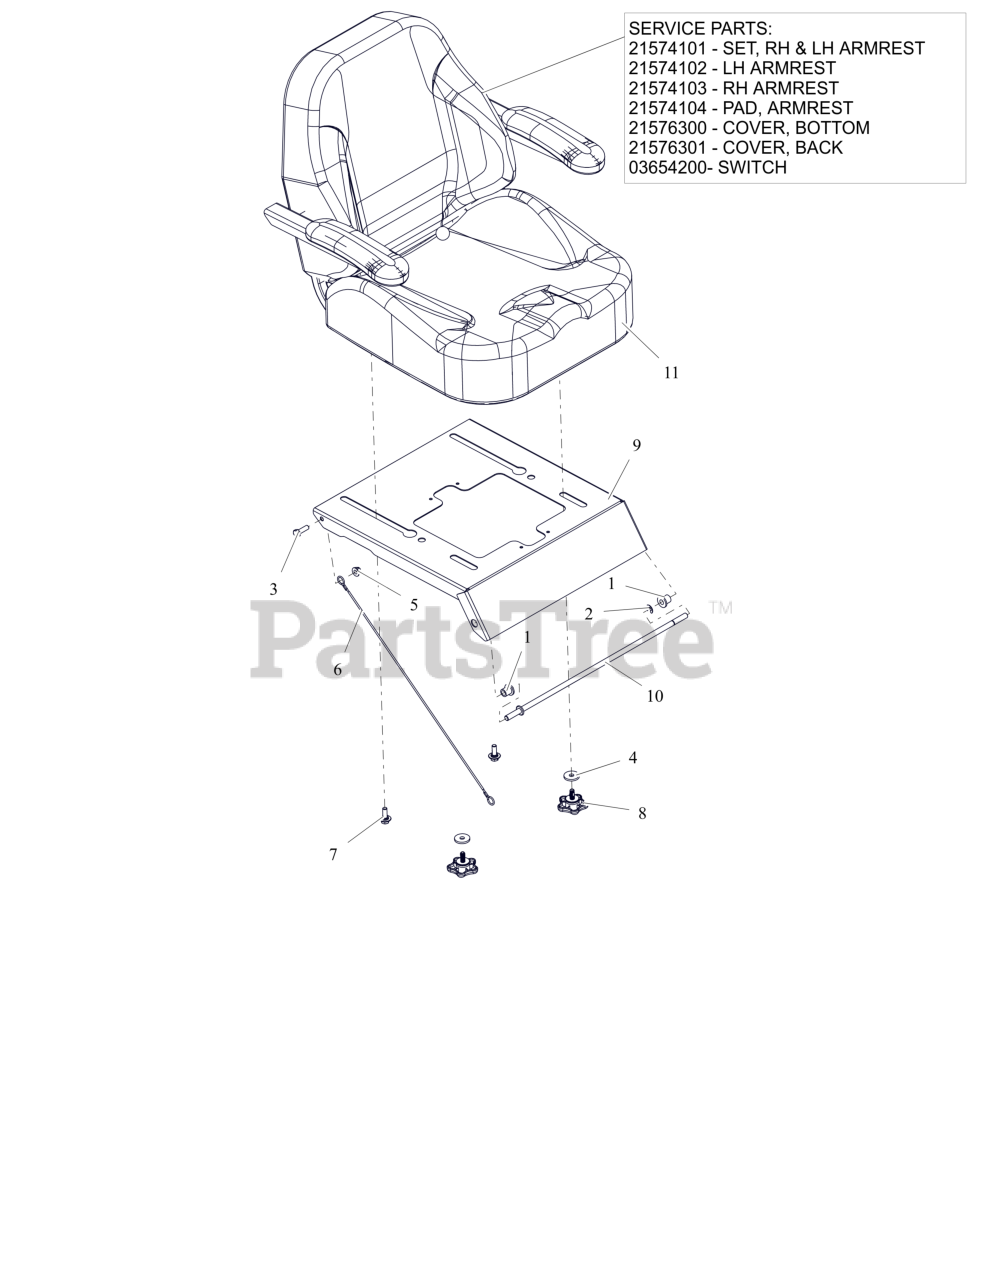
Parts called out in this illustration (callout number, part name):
1	BSHG-FLG .38X.580X.667X.750
2	RG-RTNG-EXT .375X.035 TYP E
3	BLT,HEX .31-18X1.00 G5 ZCC
4	WSHR, FLT .340X1.125X.135 ZCC
5	NUT,LK-NYL-FLG .31-18 G5ZC120
6	LANYARD, SEAT CABLE .093X19.5
7	BLT, SHLDR .31-18 X .100
8	KNOB, WING STUDDED
9	PLATE, SEAT (FASTENER SLIDE) (ORANGE)
10	ROD- SEAT PIVOT
11	SEAT- IKON XD
11	SET, RH & LH ARMREST
11	LH ARMREST
11	RH ARMREST
11	PAD, ARMREST
11	COVER, BOTTOM
11	COVER, BACK
11	SWITCH- SEAT
